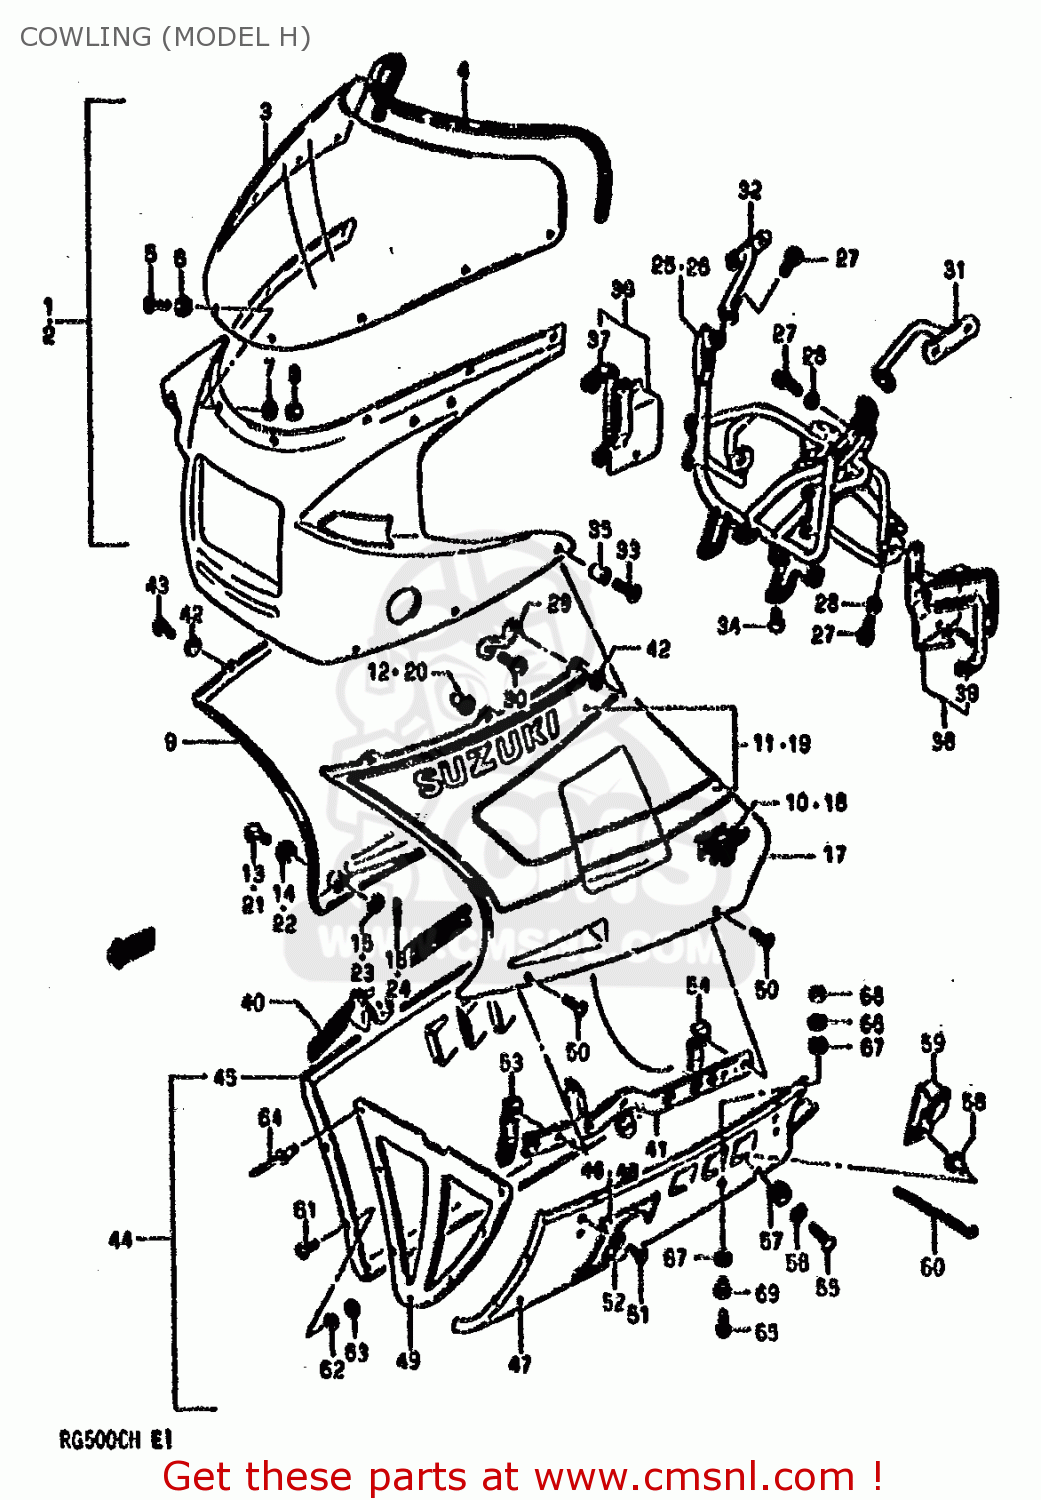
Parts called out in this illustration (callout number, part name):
1	COWLING, BODY
2	COWLING ASSY (BLUE)
3	WINDOW,COWLING
4	MOLDING
5	SCREW(5X14)
6	CUSHION
7	WASHER,5MM
8	NUT 8MM
9	COWLING,SIDE RH (BLACK/RED)
10	EMBLEM
11	TAPE SET,RH
12	NUT,COWLING COVER
13	HEAD,COWLING FASTENER
14	WASHER,COWLING FASTENER
15	E-RING
16	PIN
17	COWLING,SIDE LH (BLACK/RED)
18	EMBLEM
19	TAPE SET,LH
20	NUT,COWLING COVER
21	HEAD,COWLING FASTENER
22	WASHER,COWLING FASTENER
23	E-RING
24	PIN
25	BRACE,COWLING
26	BRACE,COWLING
27	BOLT
28	WASHER,LOCK,8.
29	BRACKET,COWLING UPR
30	BOLT
31	BRACKET,RR VIEW MIRRORR,L
32	BRACKET,RR VIEW MIRRORR,R
33	SCREW(6X25)
34	SCREW(6X16)
35	SPACER
36	COVER,COUPLER RH
37	MOLDING
38	COVER,COUPLER LH
39	MOLDING
40	BRACKET,COWLING LWR,R
41	BRACKET,COWLING LWR,L
42	WASHER(7X14X1.2)
43	SCREW(6X30)
44	COWLING,UNDER (BLUE)
45	COWLING,UNDER RH
46	EMBLEM
47	COWLING,UNDER LH
48	EMBLEM
49	COVER,CENTER
50	SCREW(6X12)
51	SCREW
52	WASHER
53	BRACKET
54	BRACKET
55	SCREW
56	WASHER(6,5X22X1.6)
57	CUSHION
58	SPACER
59	BRACKET
60	CLAMP
61	SCREW
62	WASHER
63	NUT 4MM
64	RIVET
65	SCREW
66	WASHER
67	CUSHION,UNDER COWLING BOTTOM
68	NUT
69	SPACER
